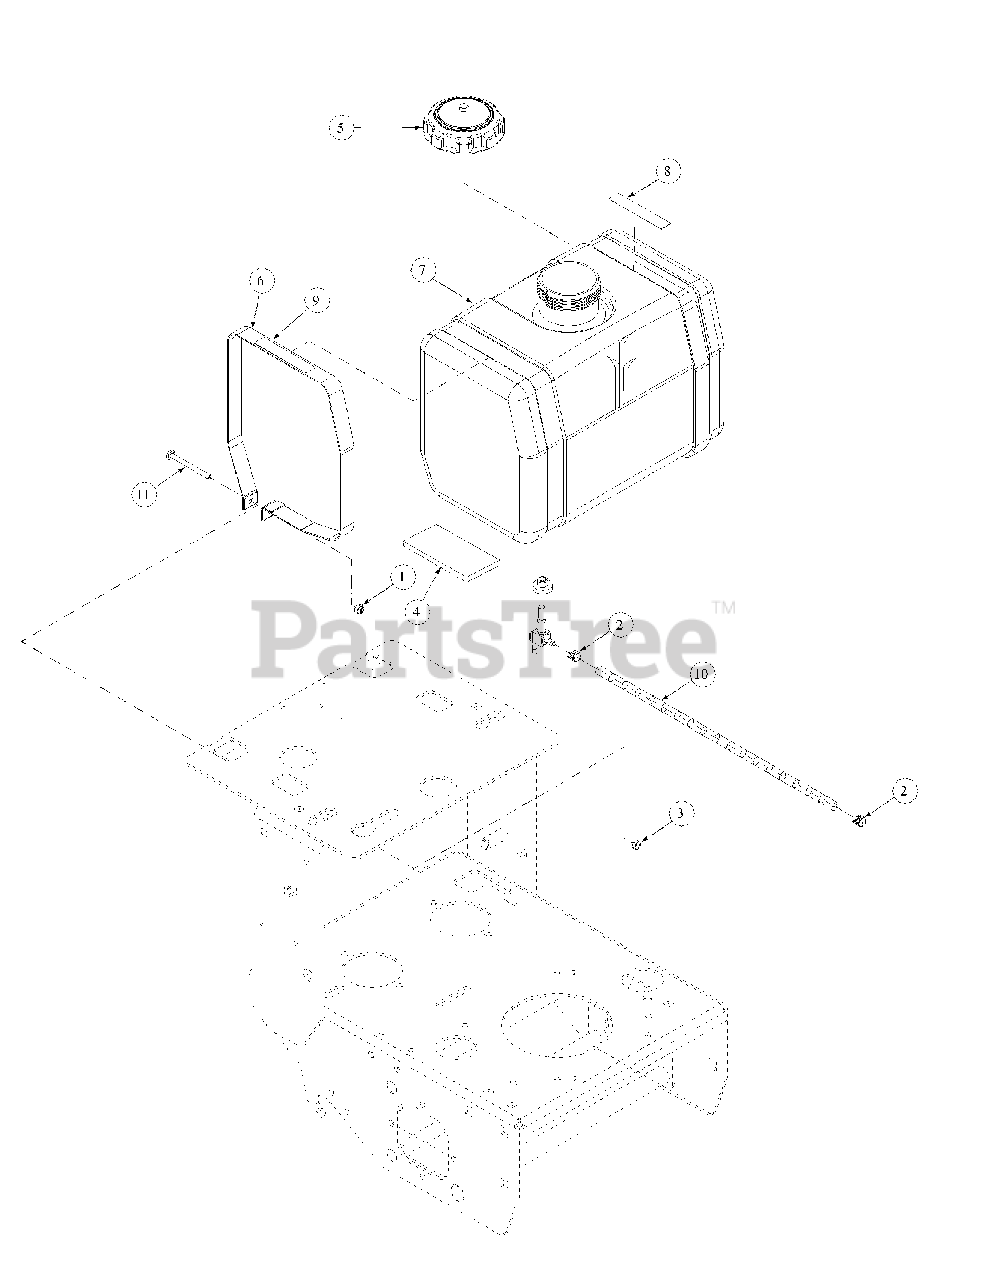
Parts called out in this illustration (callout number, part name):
1	Lock Nut, Nylon Insert, 1/4-20 Grade A
2	Uni-Clamp, #5077-136
3	Nut, 1/4-20, Grade A
4	Stop Pad, Rubber
5	Fuel Cap, 3.5
6	Fuel Tank Strap
7	Fuel Tank
8	Mower Warning Label, Turn Off Engine
9	Mower Instruction Label, Fuel Valve
10	18" Fuel Hose
11	Carriage Bolt, 1/4-20 x 3.00 Grade 5
